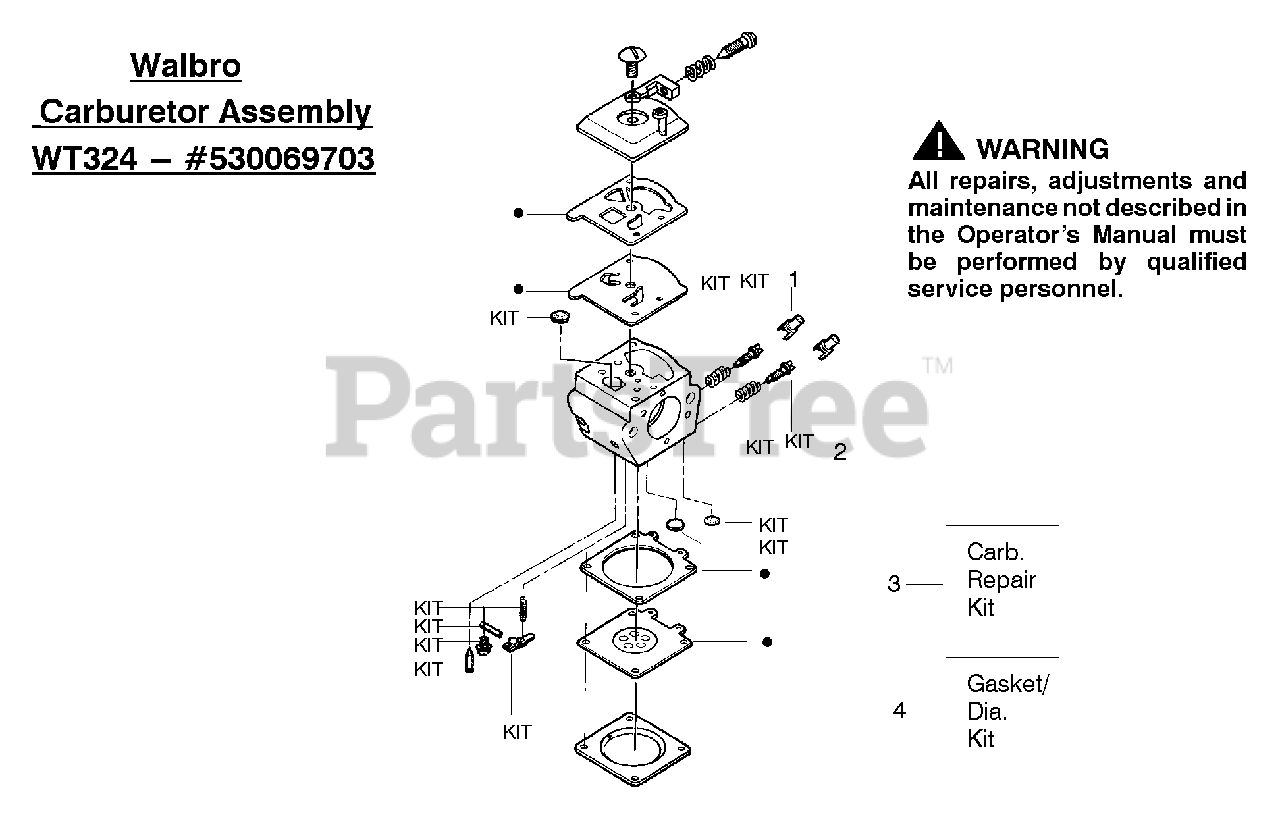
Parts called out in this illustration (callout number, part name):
1	Limiter Cap-High (brown)
2	Limiter Cap-Low (tan)
3	Walbro (WT324) Carburetor Repair Kit
4	Walbro (WT324) Gasket Diaphragm Kit
530069703	Carburetor Assembly Walbro WT324
